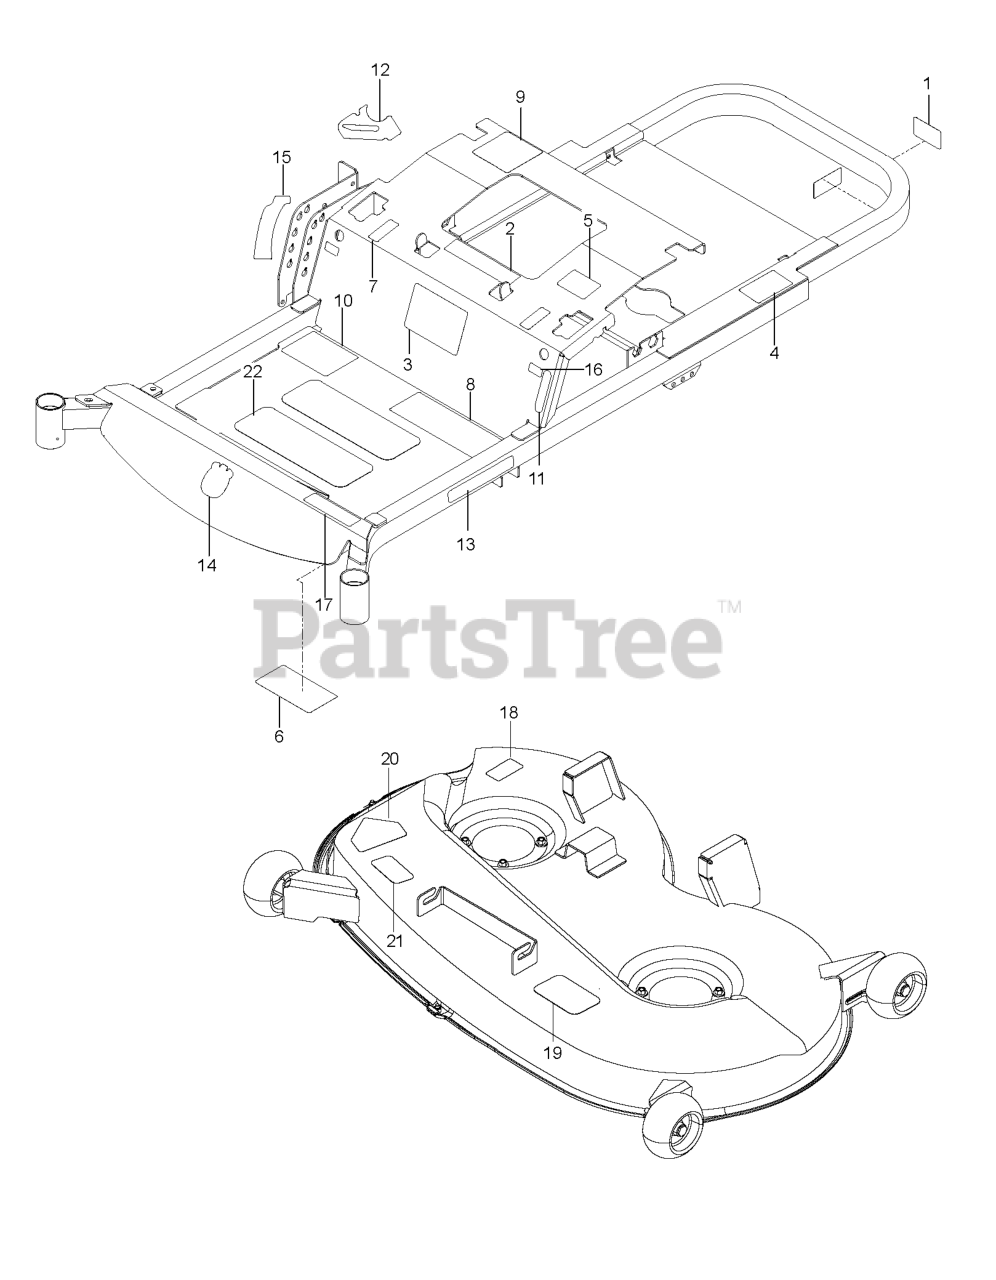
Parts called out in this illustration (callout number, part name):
1	DECAL, PROP. 65
2	EURO DECAL-BATTERY WARNIN6
3	DECAL, START
4	DECAL, DO NOT TOW
5	DECAL, EXITING MOWER
6	DECAL, SERVICE
7	DECAL, MOTION CONTROL
8	DECAL, SAFETY WARNING
9	DECAL, CUSTOMER RESPNSIBILITY
10	DECAL, WARNING
11	DECAL, PARK BRAKE
12	DECAL, IGNITION CONSOLE
13	DECAL.HOOD.LOGO.ORANGE.HUSQVAR
14	DECAL, CROWN H 70MM
15	DECAL, HEIGHT
16	DECAL, F.S.T.
17	DECAL, RZ4619
18	DECAL, CAUTION
19	DECAL, BELT ROUTING
20	DECAL, CPSC
21	DECAL, EURO SEVERING
22	ANTI-SKID PAD
